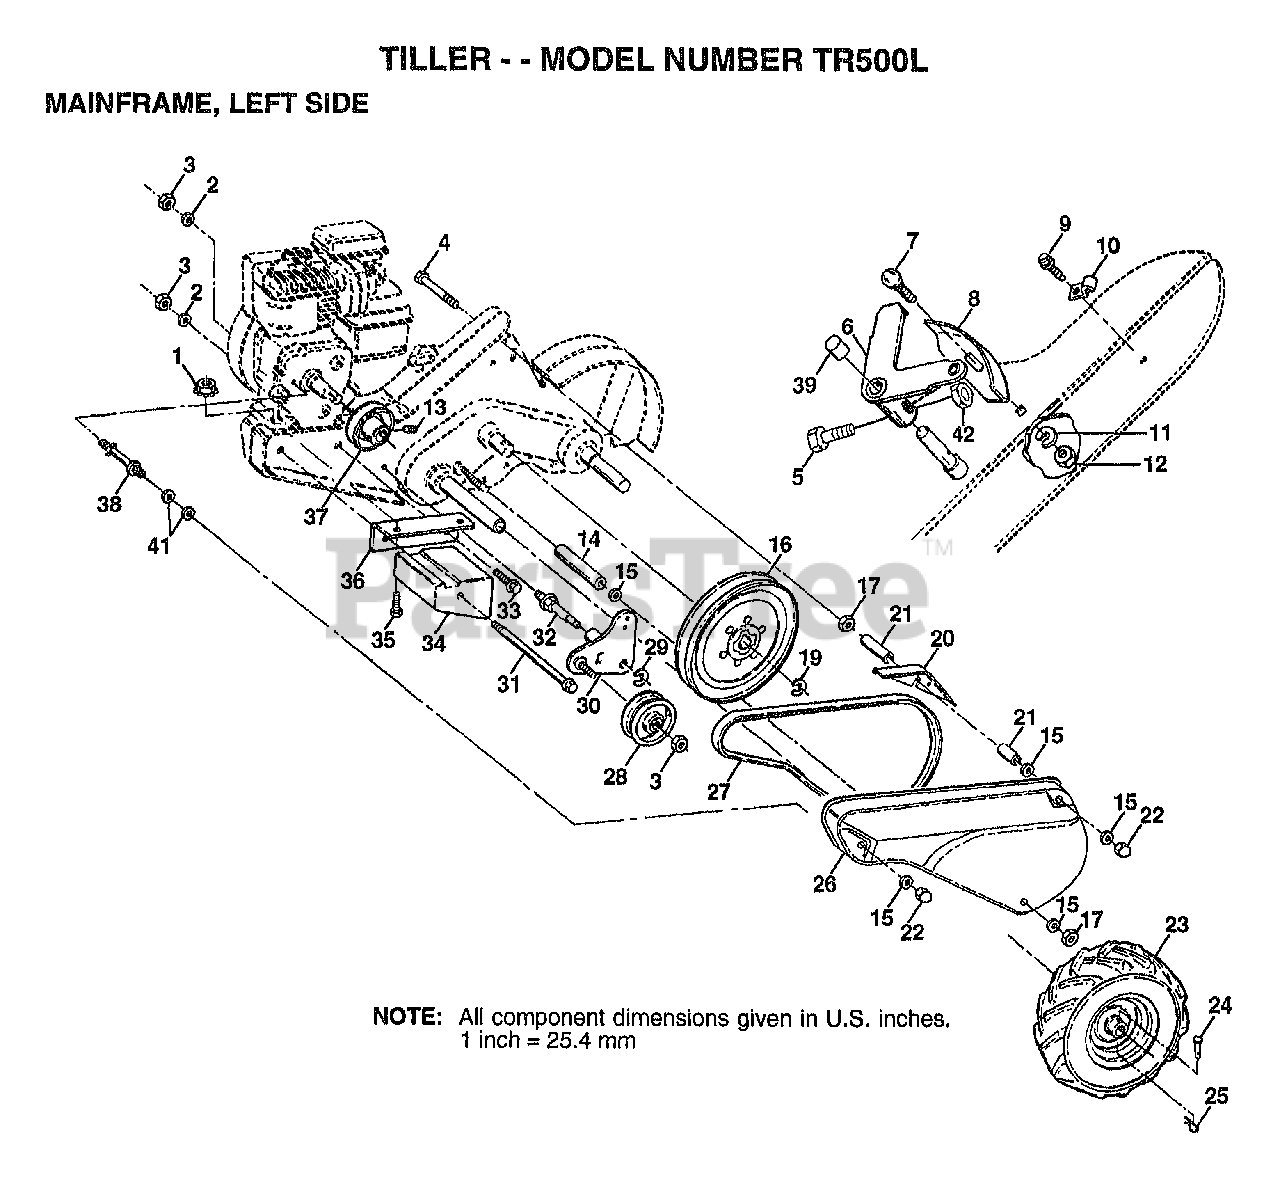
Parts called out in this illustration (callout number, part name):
2	LOCKWASHER
3	NUT.HEX.3/8-16UNC
4	BOLT TI
5	"SCREW-LEVER,SHI"
6	LEVER ASM CRT
7	BOLT
8	PANEL TI
10	CONDIUT CLIP T
11	LOCKWASHER
13	SET SCREW
14	SPACER
15	WASHER
16	SHEAVE.TRANS.
17	NUT.HEX.5/16-18
20	GUARD CRT
21	SPACER.SPLIT
22	NUT TI
23	TIRE.CHV.13X5.0-6
24	RIVET.DRILL.1.75
25	RETAINER M
26	GUARD.BELT.PNT.
27	BELT-V
28	PULLEY-IDLER TI
29	KLIP RING
30	BRACKET ASM IDLER
31	BOLT CRT
32	SHIFT ARM CRT
33	BOLT
34	COUNTERWEIGHT CRT
35	BOLT.HEX.5/16-1.5
36	BRACKET LH CRT
37	ENGINE SHEAVE
38	STUD.GUARD.BELT
39	CAP PLUNGER BLACK
41	WASHER
42	LOCKNUT
